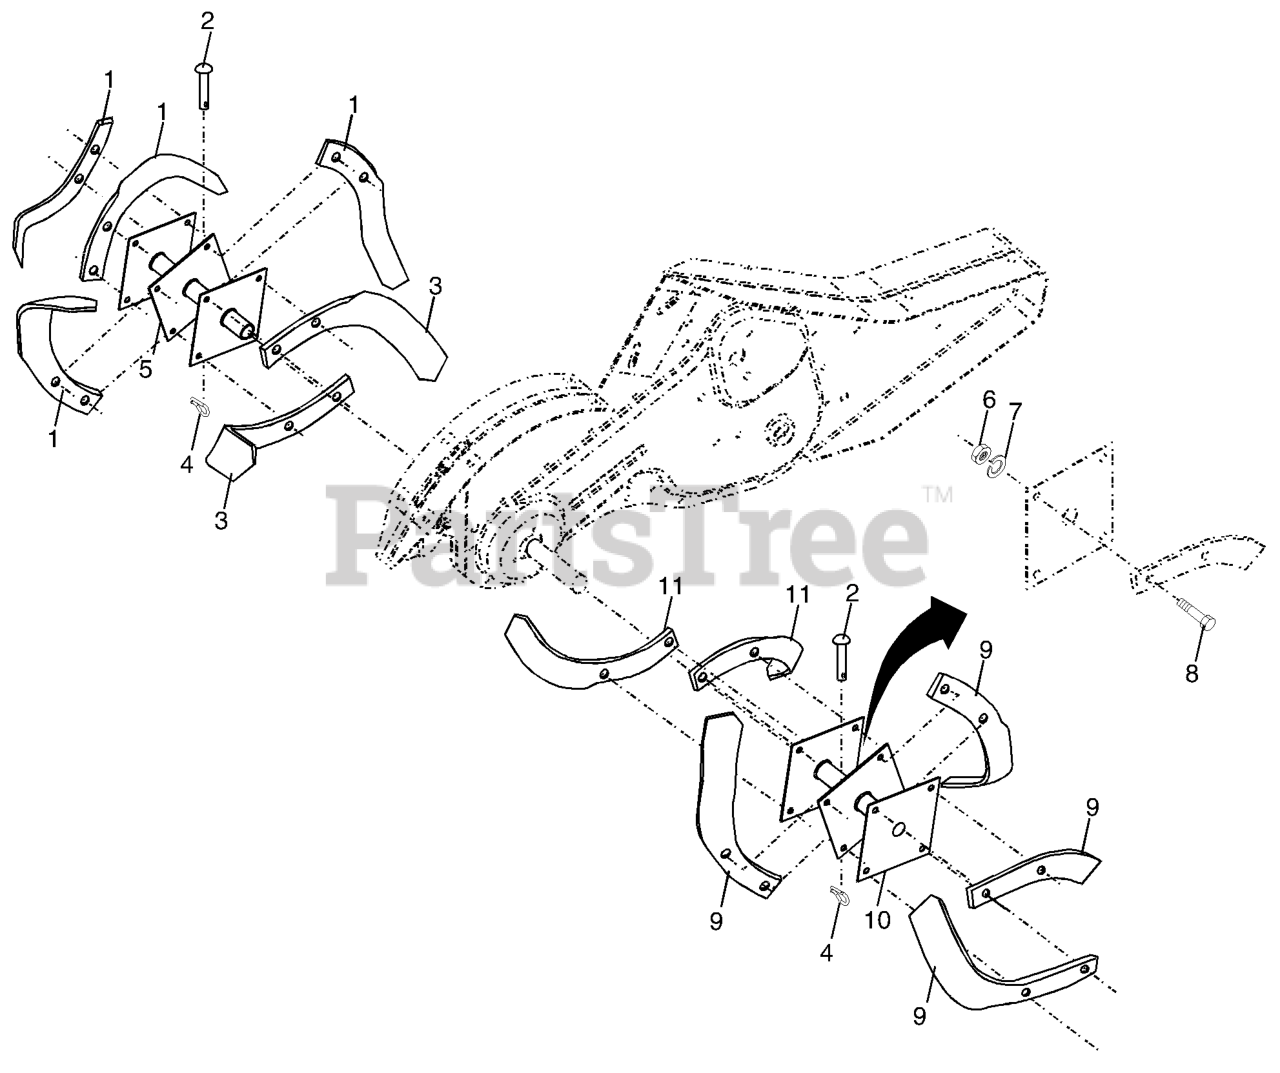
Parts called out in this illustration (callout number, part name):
1	TINE TI
2	PIN RETAINING SCREW
3	TINE.LH.12"(72L)
4	SPRING RETAINER
5	HUB.&.PLATE.ASM.LH
6	NUT
7	WASHER, LOCK 3/8
8	BOLT.HEX.001X20.37-24X1.ZINC
9	TINE TI
10	HUB & PLATE ASM RH
11	TINE.RH.12"(72R)
